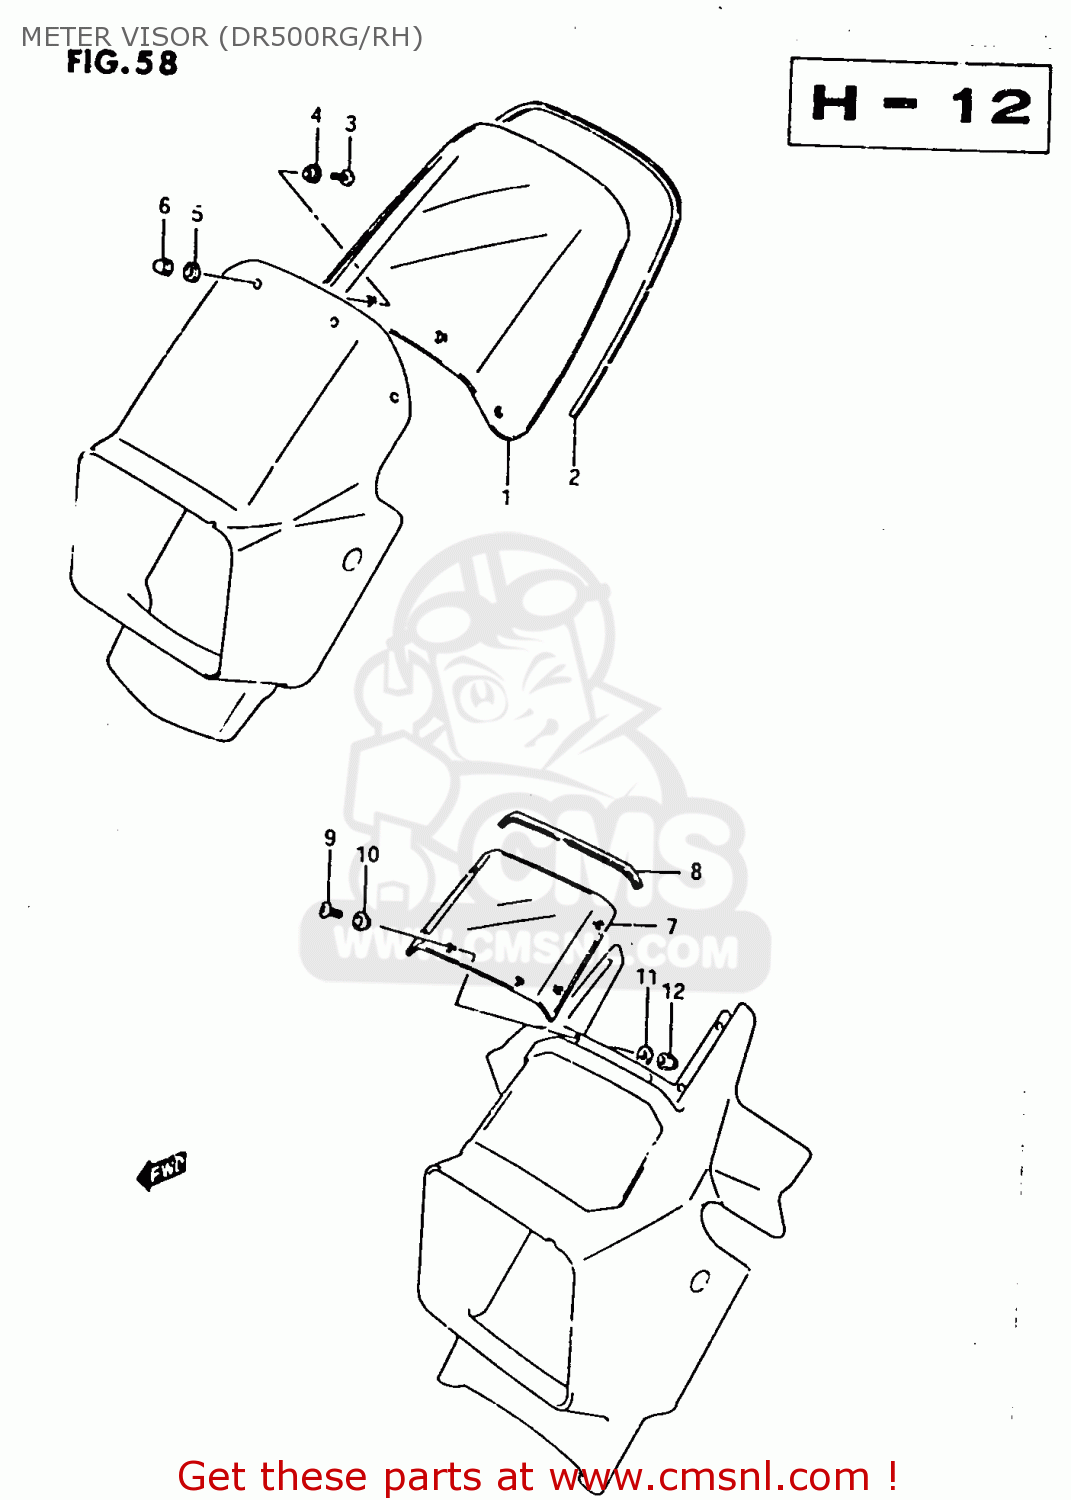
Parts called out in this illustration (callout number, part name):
1	VISOR, METER
2	MOLDING (L:545)
3	SCREW 5X10
4	CUSHION
5	WASHER,5MM
6	NUT
7	VISOR, METER
8	MOLDING
9	SCREW 5X10
10	CUSHION
11	WASHER,5MM
12	NUT
